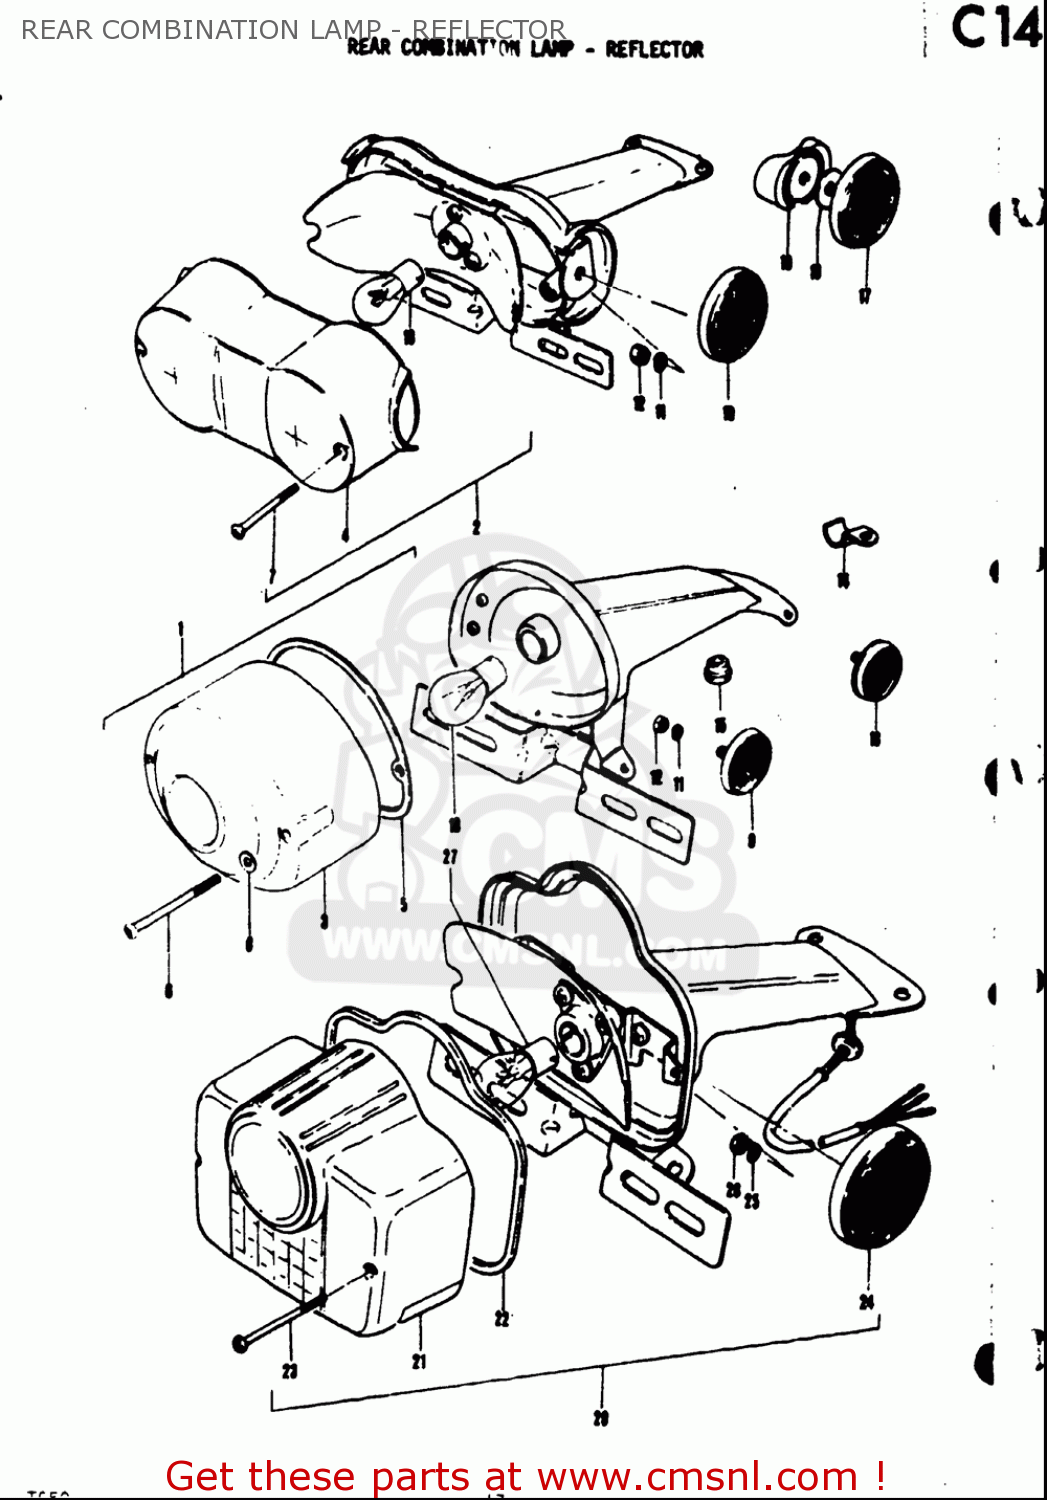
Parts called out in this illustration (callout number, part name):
3	LENS,RR COMBINATION LAMP
4	LENS,RR COMBINATION LAMP
7	SCREW
11	WASHER,LOCK
12	NUT
13	BULB(6V17/5.3W,STANLEY,A4813)
14	CLAMP
17	REFLEX REFLECTOR,RR
18	WASHER(6.5X20X1.6)
19	SPACER
21	LENS
22	GASKET (NAS)
25	WASHER,LOCK
26	NUT
27	BULB(6V32/3CP,STANLEY)
